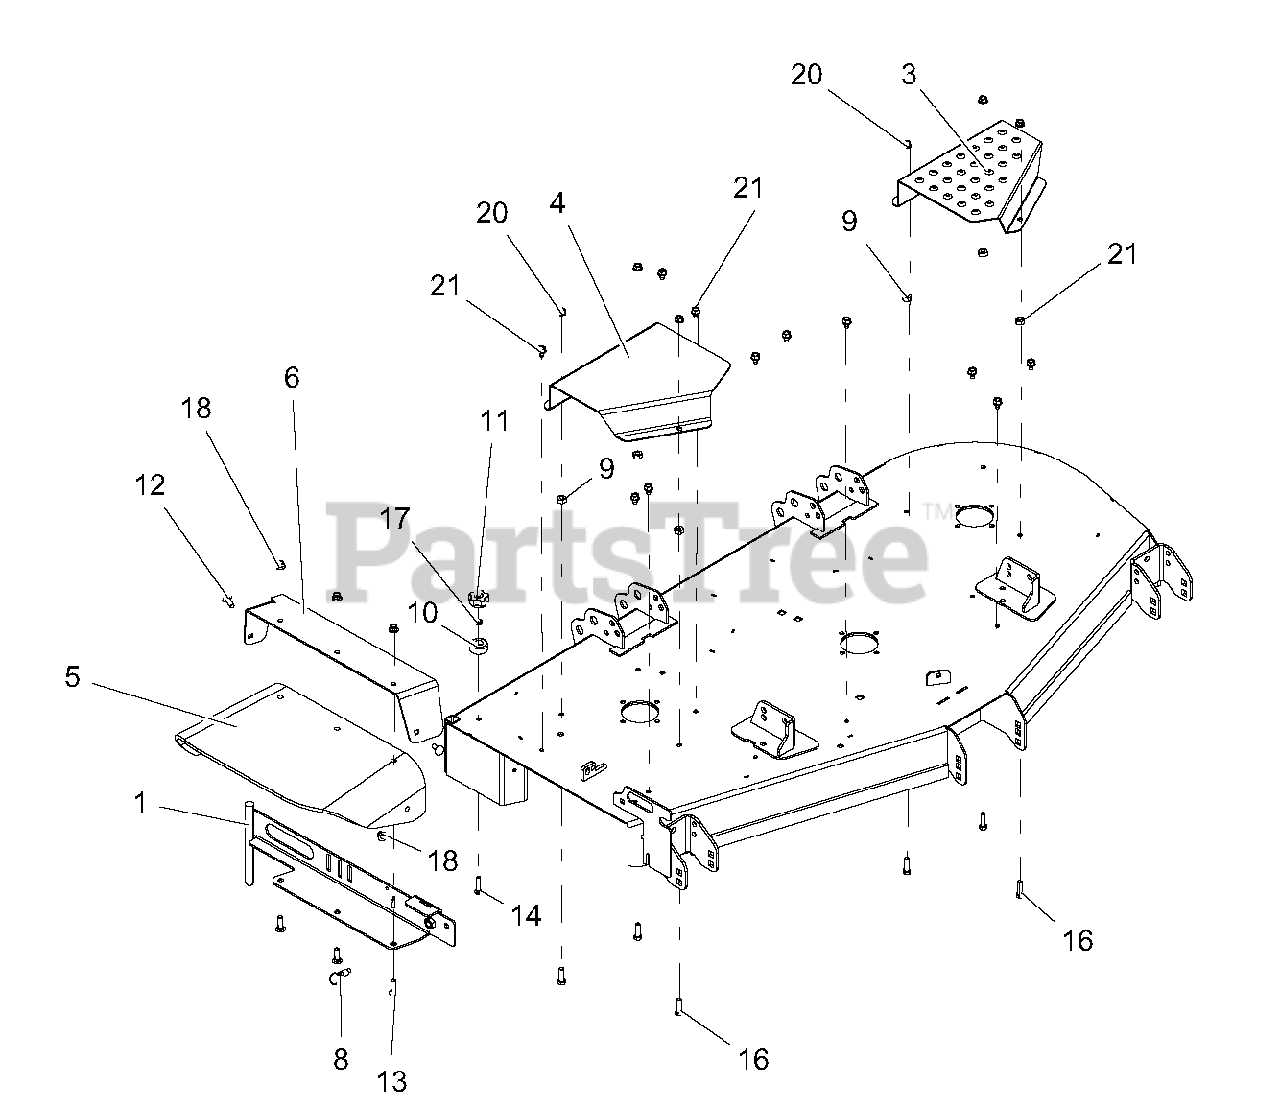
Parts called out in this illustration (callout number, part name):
1	WLDMT, 52"-60" DISCH CHUTE MTG-RED
3	GUARD, 60" LH DECK BELT-BLACK
4	GUARD, 60"-66" RH DECK BELT-BLACK
5	CHUTE, RUBBER DISCHARGE
6	SUPPORT, CHUTE MOUNTING BRACKET-RED
8	PULL PIN,.50-13THDX.310 PLNGR
9	NUT-HEAVY HEX .38-16 YWZC
10	BUMPER, RECESSED 1.50 X .63 W/.31 HOLE
11	KNOB, CLAMPING
12	@BLT-RDHDSQNK .38-16X1.00 G5 YWZC
13	@BLT-RDHDSQNK .38-16X1.25 G5 YWZC
14	@BLT-RDHDSQNK .31-18X1.50 G5 YWZC
16	BLT-HEX .38-16X1.25 GR5 YWZC
17	@NUT-LK-CTR .31-18 YWZC
18	NUT-LK-NYL-FLG .38-16 YWZC
20	@NUT-SPNLK-FLG .375-16 YWZC
21	SCR-TAP .38-16X.50 HWH TR YWZ
